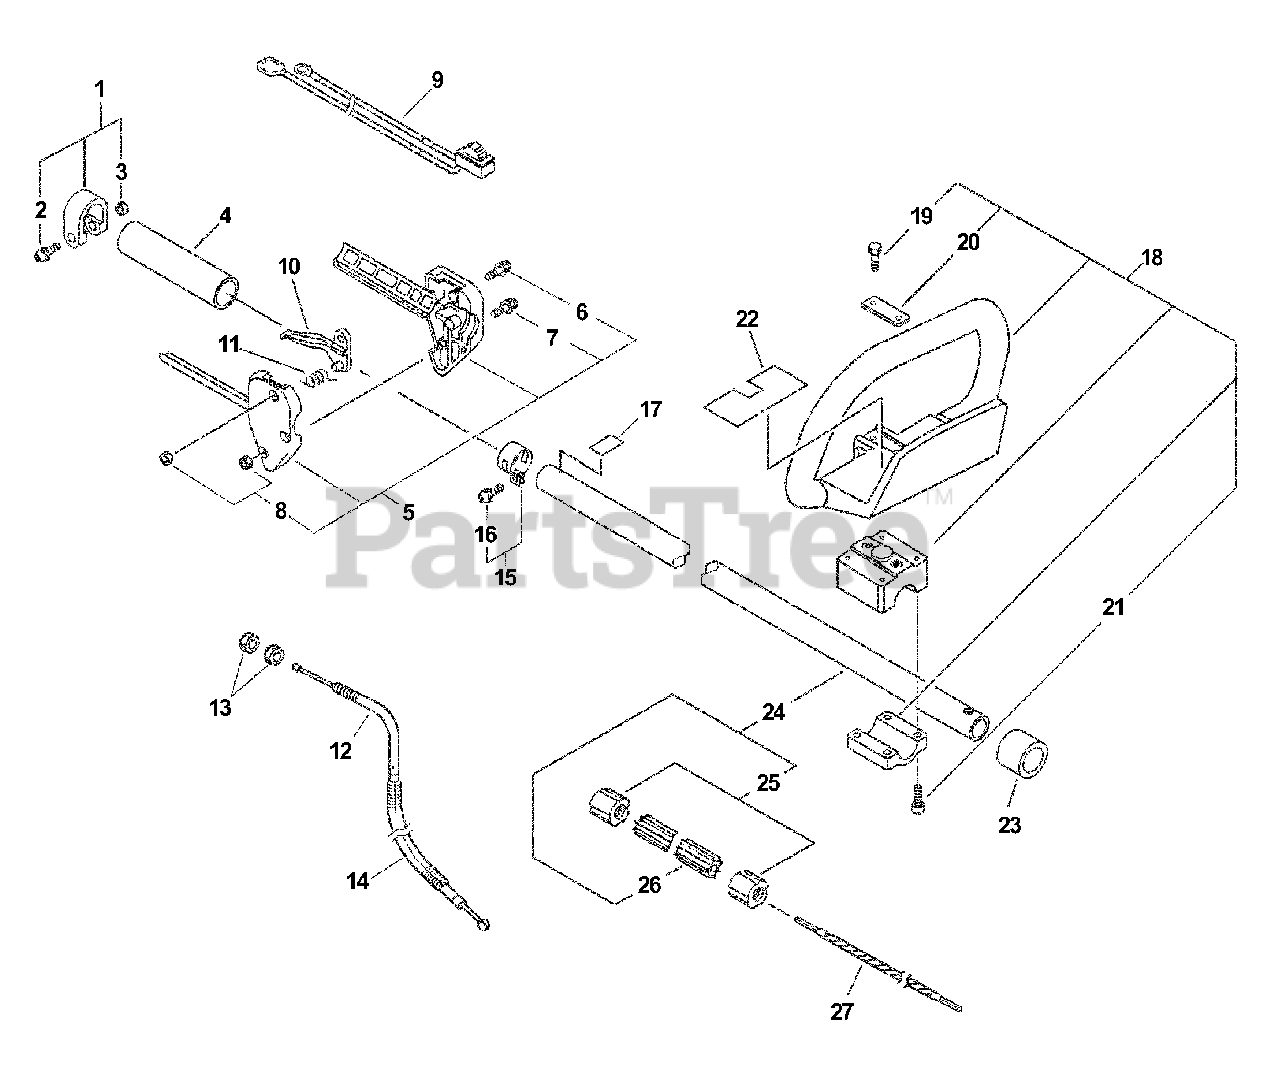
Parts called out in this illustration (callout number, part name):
1	CLAMP
2	SCREW 5×28
3	NUT M5
4	GRIP, HANDLE
5	THROTTLE BRACKET SET
6	SCREW 5×35
7	SCREW 5×25
8	NUT M5
9	SWITCH ASSY, ON-OFF
10	TRIGGER, THROTTLE
11	SPRING, TORSION
12	CABLE, THROTTLE
14	TUBE, PROTECTIVE - CORRUGATED
15	CLAMP KIT
16	SCREW 5×14
17	LABEL - ALIGNMENT
18	FRONT HANDLE ASSY
19	BOLT 5×30
20	PLATE, EYE
22	LABEL, CAUTION
23	COLLAR
24	MAIN PIPE ASSY
26	LINER - FLEXIBLE
27	DRIVESHAFT - FLEXIBLE
